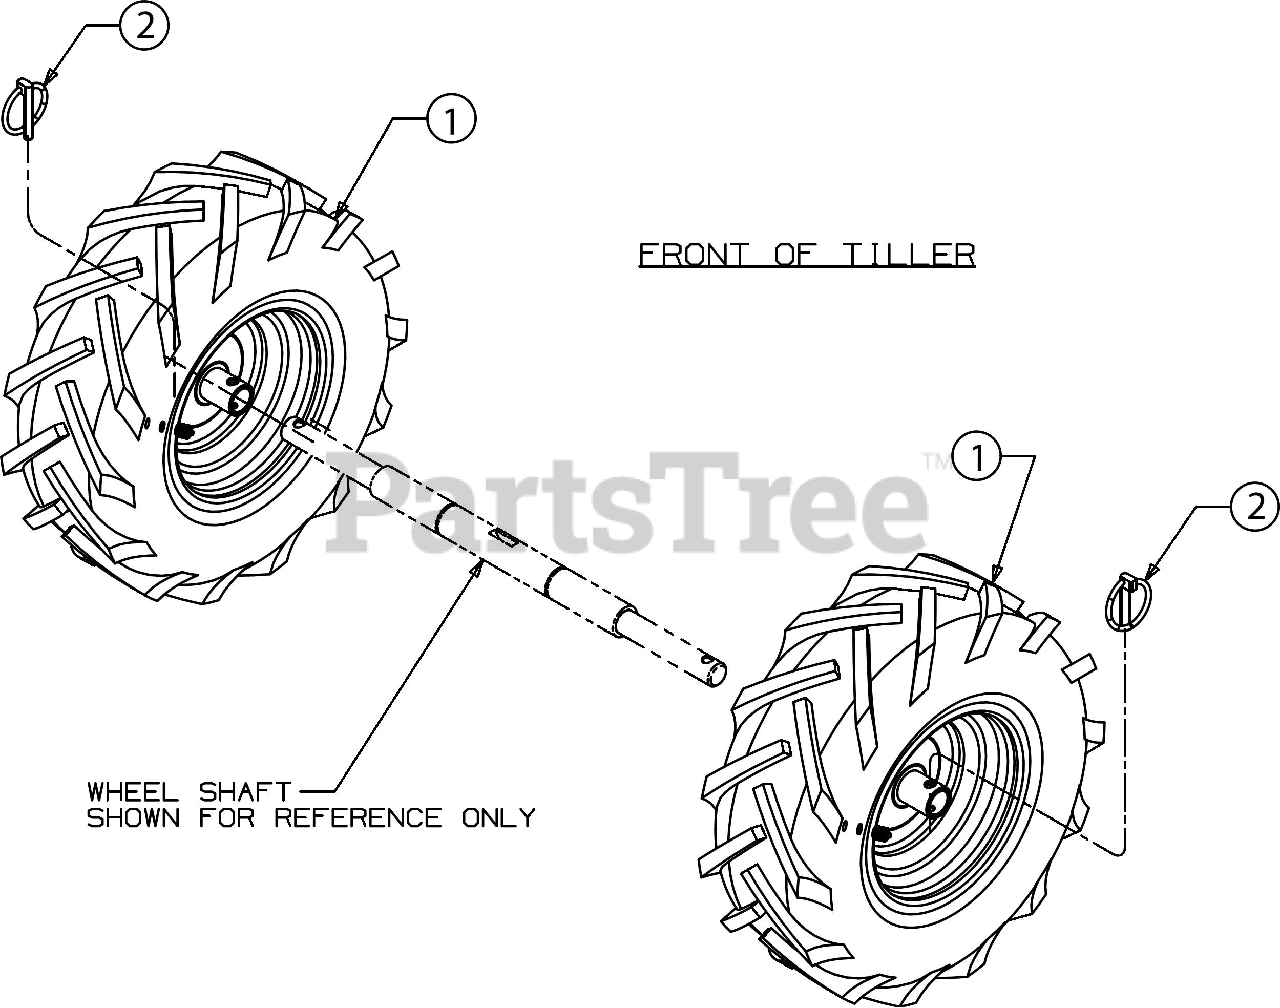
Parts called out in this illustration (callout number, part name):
1	WHEEL ASSEMBLY (13 X 5 X 6)
1	TUBELESS VALVE
1	TIRE 13 X 5.0 X 6.00
